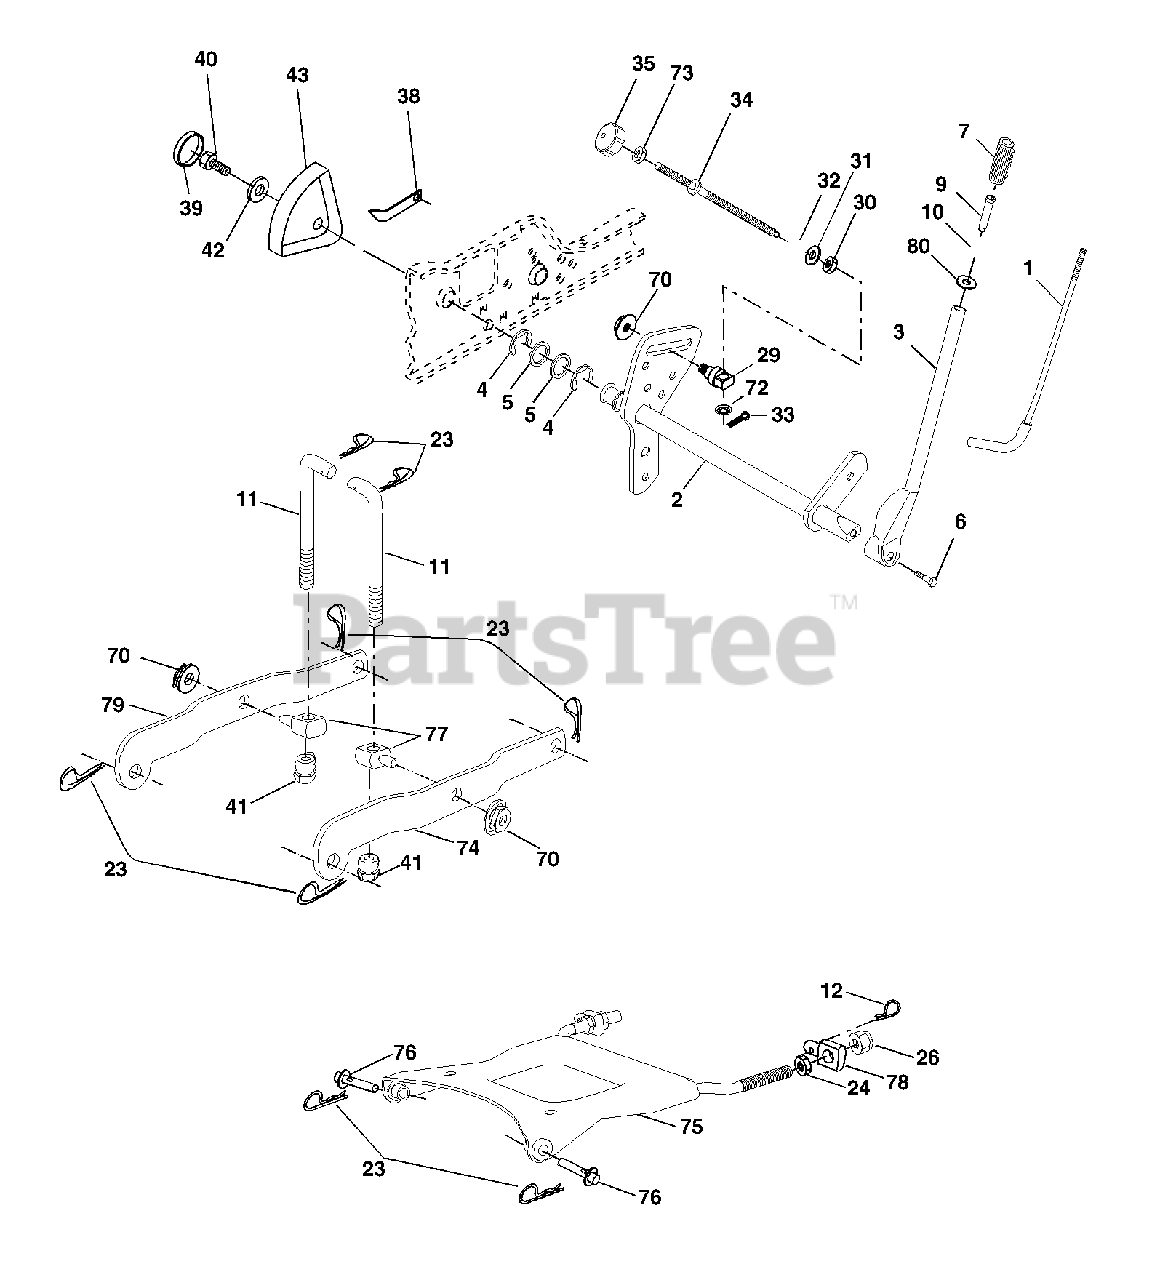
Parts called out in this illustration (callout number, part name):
1	Rod Asm., Lever
2	Shaft Asm., Lift Vgt
3	Lever Asm., Lift Rh
4	E-Ring Truarc #5133-87
5	Washer 29/32 x 1-1/4 x 16 Ga.
6	Bolt, Fin Hex 3/8-16 x 1-1/2
7	Grip, Handle
8	Button, Plunger
9	Plunger, Lever Lift
10	Spring 2-1/8"
11	Link Lift
12	Retainer, Spring
23	Retainer, Spring
24	Nut, Jam Hex 1/2-13 Unc
26	Nut, Lock W/Wsh 1/2-13 Unc
29	Trunnion Infin Height
30	Nut, Special
31	Washer 13/32 x 5/8 x 16 Ga.
32	Spring, Compression Inf Hgt
33	Pin, Cotter 3/32 x 1/2
34	Rod, Adj Lift
35	Knob, Inf 3/8-16 Unc
38	Pointer Height Indicator
39	Plug, Hole Blk. 1.485/1.515 Dia.
40	Screw 5/16-18 x 1
41	Nut, Lift Link 7/16-20
42	Washer 11/32 x 1-1/2 x 10 Ga.
43	Scale, Indicator Height
70	Nut Hex Flange Lock
72	Nut Push Phos & Oil
73	Nut, Hex Jam 3/8-16 Unc
74	Arm Suspension Rear RH
75	Plate, Asm, Susp, Front
76	Pin Flange
77	Trunion Susp Arm
78	Trunnion, Front, Susp
79	Arm, Suspension LH
80	Washer 1/4 x 5/8 x .062
